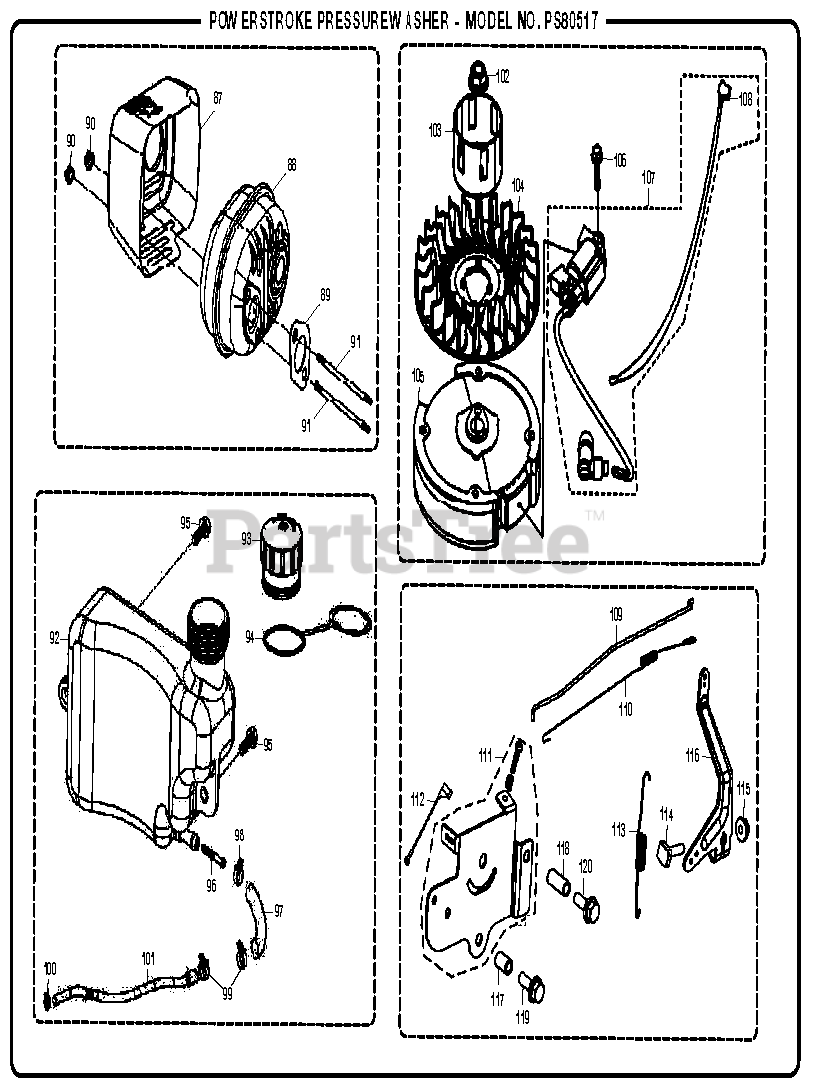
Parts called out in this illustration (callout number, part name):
87	Muffler Outer Cover
88	Muffer Assembly
89	Exhaust Outlet Gasket
92	Fuel Tank Assembly
94	Fuel Cap Chain
100	Clamp
102	Flywheel Nut
103	Starter Pulley
105	Flywheel Assembly
107	Ignition Coil Stop Wire
108	Ignition Coil
109	Governor Rod
110	Throttle Valve Return Spring
111	Throttle Control Bottom Plate
112	Stop Engine Switch Ground Wire
113	Governor Spring
114	Governor Support Bolt
116	Governor Support Assembly
119	Hex Flange Nut
120	Hex Flange Nut
